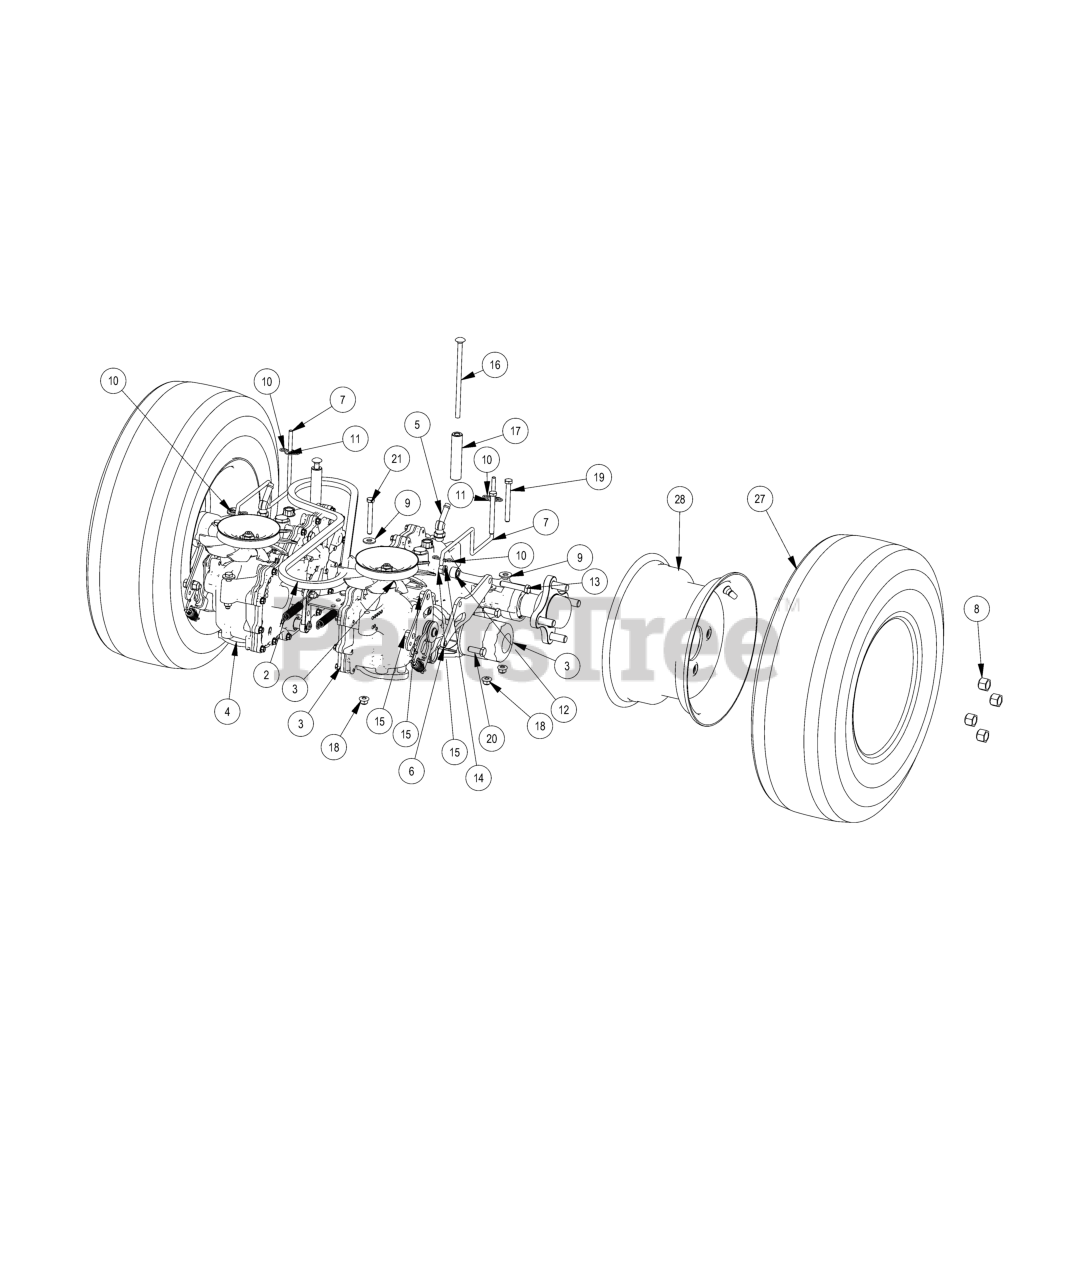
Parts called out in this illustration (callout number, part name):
1	2020 36" Brake Bracket 2020 36" Stand On
2	2019 Renegade Pump Belt
3	ZT Transaxle Left 3100
4	ZT Transaxle Right 3100
5	ZT Fitting, 3/8 x 3/8 45 Degree, 4603-6-6
6	Control Arm Plate 2019 Stand On
7	2019 Stand On Neutral Rod
8	Acorn Lug Nut
9	5/16 USS FLAT WASHER (7/8 OD) ZINC
11	1/4 USS FLAT WASHER (3/4 OD) ZINC
12	ACS Spacer 3/4x3/8x1/2
13	3/8-16 X 2 HEX CAP SCREW (GR.5) ZINC
14	3/8 SPLIT LOCKWASHER ZINC
15	3/8-16 HEX NUT ZINC
16	5/16-18 X 6 CARRIAGE BOLT (GR.5) ZINC
17	2017 Transaxle Spacer
18	5/16" Nylock Flange Nut Zinc
19	5/16-18 X 3 HEX CAP SCREW (GR.5) ZINC
20	3/8-16 X 1 GR 5 Hex Bolts Zinc
21	5/16-18 X 2-1/2 HEX CAP SCREW (GR.5) ZINC
22	1/4-20 NYLON INSERT LOCKNUT ZINC
23	1/4-20 Nylon Insert flange Nut
24	1/4-20 X 3/4 HEX CAP SCREW (GR.5) ZINC
25	1/4-20 X 1 HEX CAP SCREW (GR.5) ZINC
26	Brake Spring
27	36" Revolt Reaper Tire
28	36" Revolt Wheel
